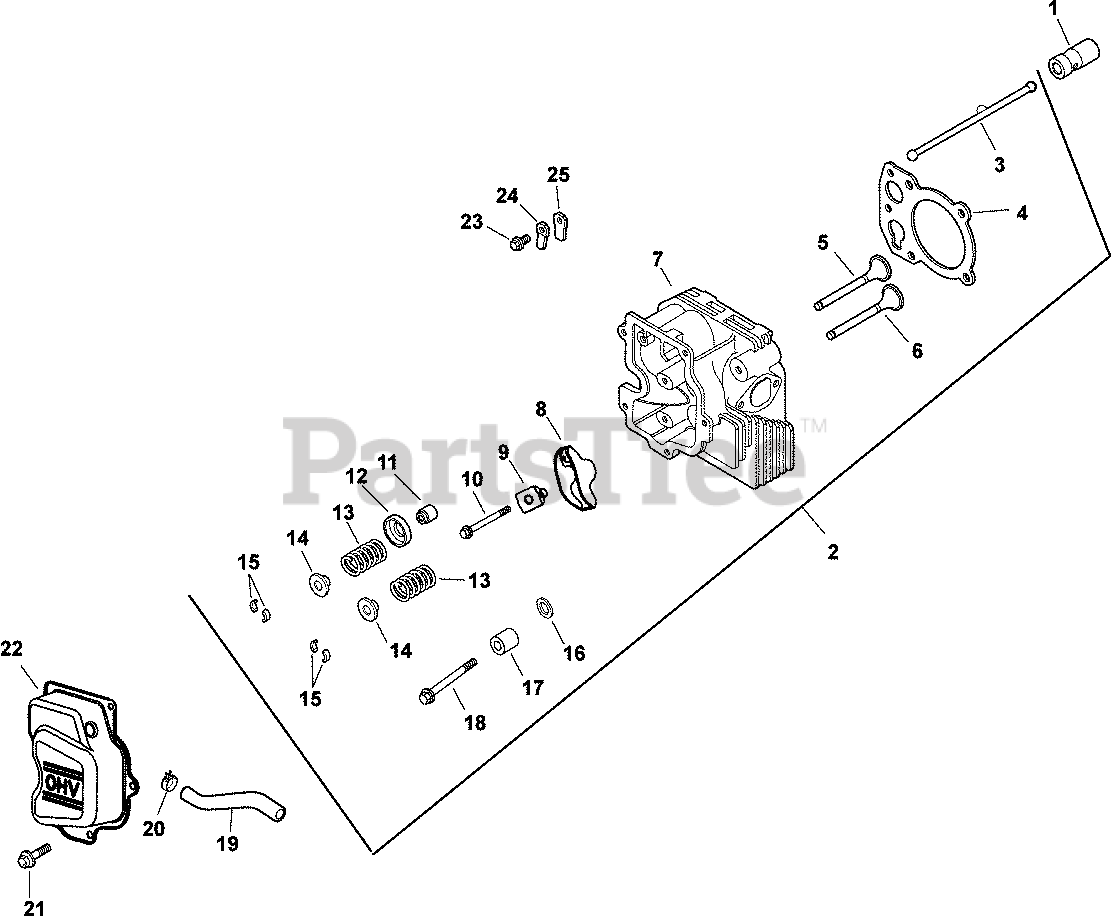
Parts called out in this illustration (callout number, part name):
1	LIFTER, HYDRAULIC VALVE-USE 25 351 10-S
2	KIT, LP CYL HD W/PORT LINER - DISCONTINUED
3	ROD, PUSH
4	GASKET, CYLINDER HEAD
5	VALVE, INTAKE
6	VALVE, EXHAUST
7	HEAD, CYLINDER - DISCONTINUED
8	ARM, ROCKER
9	PIVOT, ROCKER ARM
10	SCREW, FLG M6X1.0X34
11	SEAL, VALVE STEM - (#2503214S)
12	RETAINER, SPRING
13	SPRING, VALVE
14	RETAINER, VALVE SPRING - USE 25 173 28-S
15	KIT, RETAINER
16	WASHER, FLAT 13/32"
17	SPACER - DISCONTINUED
18	SCREW, CYLINDER HEAD (M10 X 80)
19	HOSE
20	CLAMP, HOSE (KM)-USE 25 237 31-S
21	SCREW,FLG THD FRM M6X1.0X16-(#25086397S)
22	COVER, ROCKER
23	SCREW, FLG THD FRM M5X.8X10
24	REED, BREATHER
25	RETAINER, REED
1232630-S	HOSE, BREATHER
